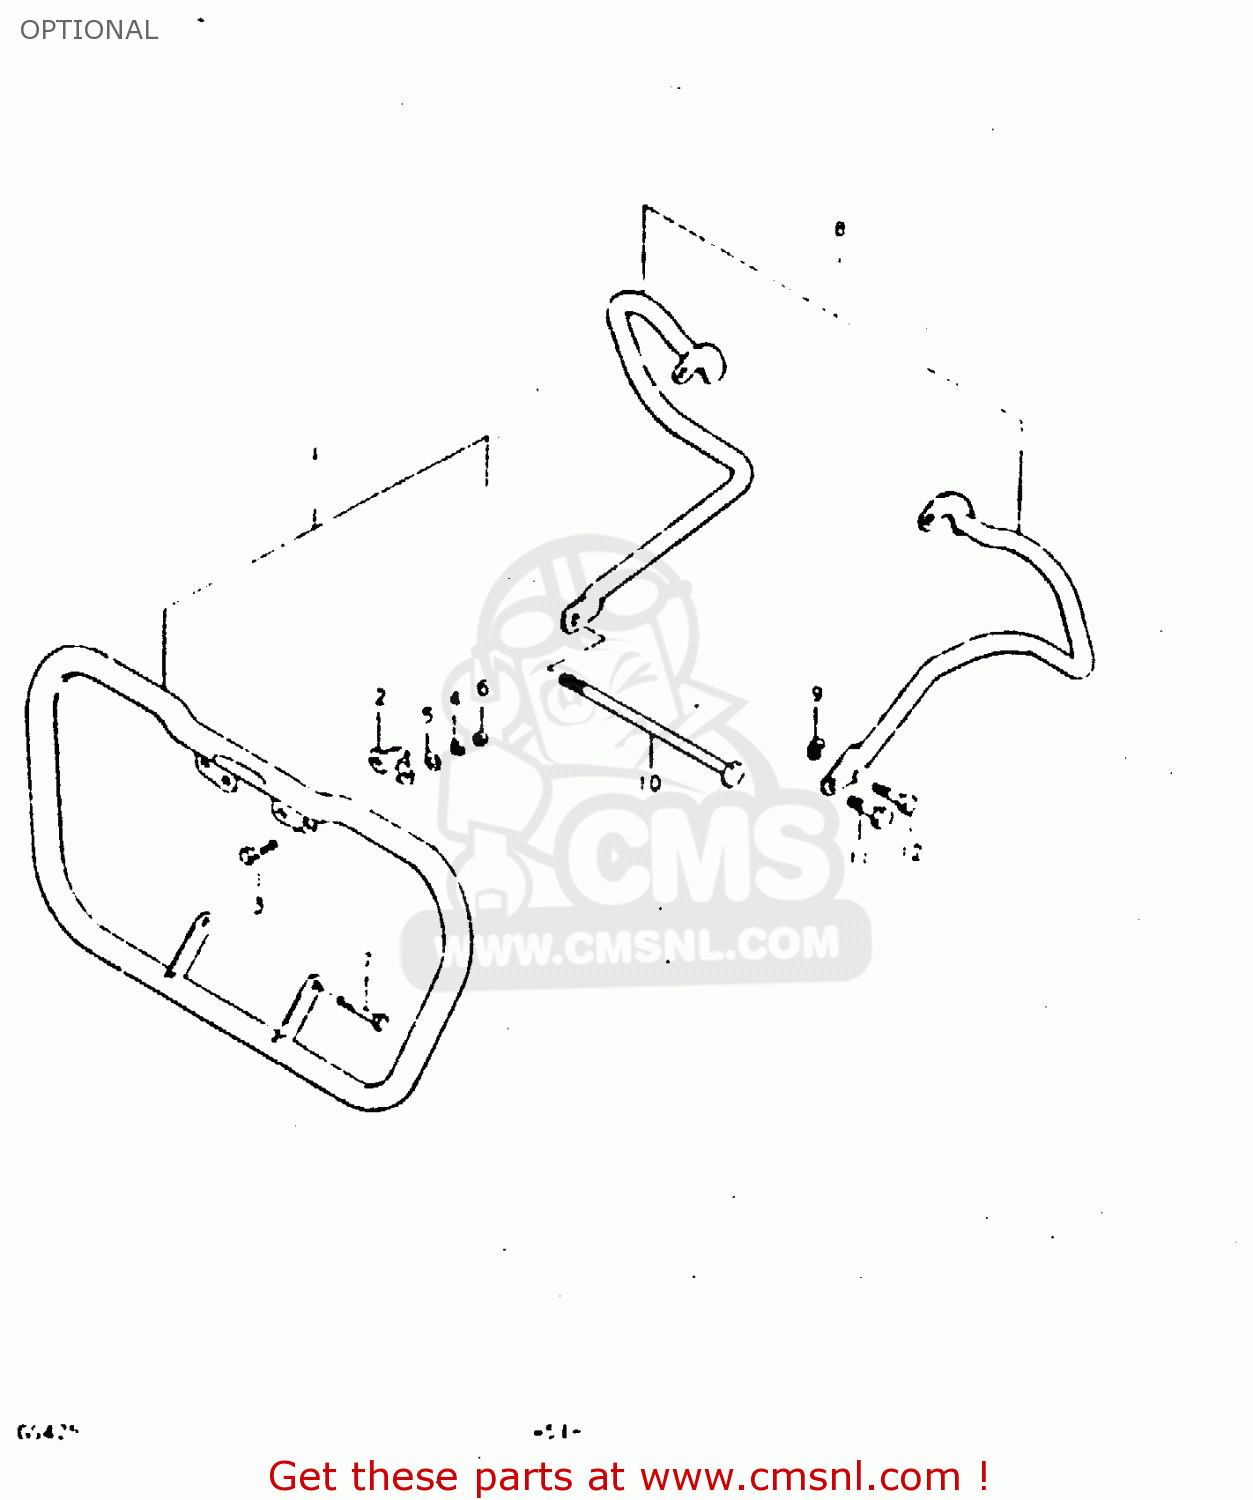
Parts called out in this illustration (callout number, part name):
1	FRONT BUMPER SET
2	PLATE, UPPER
3	BOLT
4	LOCK WASHER
5	WASHER
6	NUT
7	BOLT
8	REAR SIDE BUFFER SET
9	WASHER
10	SHAFT,REAR SWING ARM
11	BOLT(10X45)
12	BOLT 8X45
